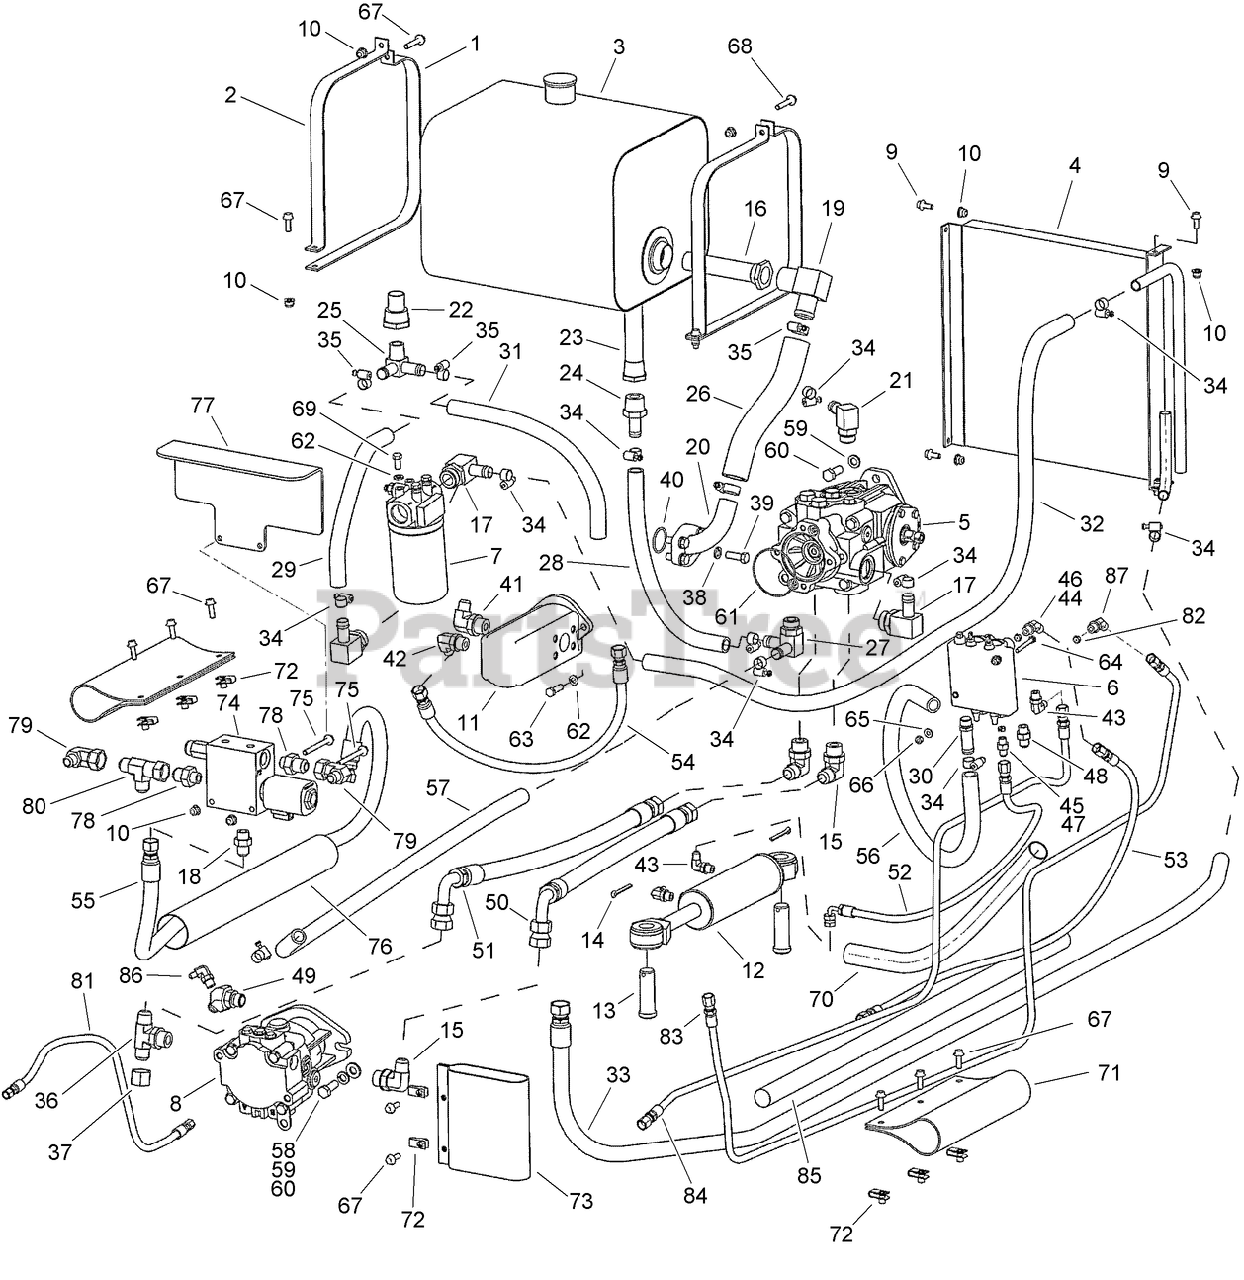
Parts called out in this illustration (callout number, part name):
1	STRAP - Tank (Lower)
2	STRAP - Tank (Upper)
3	RESERVOIR-HYDRAULIC
4	COOLER-OIL
5	HYD VARIABLE PUMP ASM
6	HYD STEERING VALVE ASM
7	OIL FILTER ASM
8	HYD PISTON MOTOR ASM
9	SCREW, METRIC FLANGE w/BODY - M8 x 20
10	NUT-TORQUE, PREVAILING
11	PUMP ASSEMBLY - Dual
12	CYLINDER ASSEMBLY - 60 (2-3/8in) ID x 127 mm (5in) Stroke, Steering
13	PIN-CLEVIS
14	PIN-COTTER
15	ELBOW-90 Adj 37FL 3/4 Tube
16	FILTER ASM
17	ELBOW - 90 Degree, 3/4 Stem End x 1-5/16-12 inch Adj O-Ring
18	CONNECTOR-Str Thd 5/8, 37FL-ORB 5/8
19	FITTING-ELBOW, 90
20	FITTING - Code 61, 90 Elbow
21	ELBOW - 90 Degree, 3/4 Stem End x 1-1/16-12 inch Adj O-Ring Boss
22	INDUCER-PRESSURE
23	FILTER ASM
24	FITTING-STRAIGHT
25	FITTING-ELBOW, LATERAL
26	HOSE - 100R3 1-1/4 in x 280 mm
28	HOSE - Hydraulic, 3/4 in x 14.5 in
29	HOSE - Hydraulic, 3/4 in x 12.5 in
30	ADAPTER - Straight, 3/4 Stem End x 3/4-16 inch Adj O-Ring
31	HOSE - 457 mm (18 inch) Long Ground Drive Pump to Reservoir (cut from D55911 bulk hose)
32	HOSE - Hydraulic, 3/4 in x 1495 mm
33	HOSE - Hydraulic, Cooler
34	CLAMP - Adj, 11/16 - 1-1/4 inch Dia
35	CLAMP - Hose Type F # 24
36	TEE - 1-1/16-12 inch Adj O-Ring Branch x Flare x Flare
38	WASHER - Spring Lock, Reg 0.438 in ZND
39	BOLT - Hex Hd .438 x 1.25 GR5 Znd
41	ADAPTOR-ELBOW
42	ELBOW-90 Deg, 1/2 to 5/8
43	ELBOW-90 DEG (ADJUSTABLE 37 DEG)
44	PLATE-ORIFICE
45	PLATE-ORIFICE
46	ELBOW-45 Adj 37FL 3/8 Tube
47	CONNECTOR-Str Thd 3/8, 37FL-ORB 3/8
48	CONNECTOR-Str Thd 1/2, 37FL-ORB 1/2
49	FITTING - 45 degree, Special
50	HOSE - 660 mm (26 inch) Long, Ground Drive Pump to Ground Drive Motor
51	HOSE - 660 mm (26 inch) Long, Ground Drive Pump to Ground Drive Motor
52	HOSE - 737 mm (29in) Long, Valve to Steering Cylinder, Closed End
53	HOSE - 940 mm (37 inch) Long, Valve to Steering Cylinder, Rod End
54	HOSE - 610 mm (24 inch) Long, Pump to Steering Control Valve
55	HOSE - 5/8 x 1600
56	HOSE - 800 mm (31-1/2 in), Return, Steering Control Valve to Dual Pump
57	HOSE - 800 mm (31-1/2 in), Return, Steering Control Valve to Dual Pump
59	WASHER-Spring Lock Reg 1/2 ZND
60	BOLT-Hex Hd 1/2 x 1-1/4 GR5 ZND
62	WASHER-Spring Lock, Reg 3/8 ZND
63	BOLT
64	BOLT-1/4-20 x 2
65	WASHER-FLAT
66	NUT - Prev Trq 1/4 GRC ZND Direct
67	SCREW-HH
68	SCREW, METRIC FLANGE w/BODY - M8 x 45
69	SCREW-HH
70	SLEEVE - Hose Retaining, Protective, Hose
71	BOOT-HOSE
73	BOOT-HOSE
74	3 WAY HYD PLOW VALVE ASM
75	SCREW, METRIC FLANGE w/BODY - M8 x 80
76	SLEEVE - Hose Protector
77	PLATE - Heat Shield
78	CONNECTOR-Str Thd 3/4, 37FL-ORB 5/8
79	FITTING-ELBOW, 90
80	FITTING-TEE
81	ASSEMBLY - Hose
82	ORIFICE
83	ASSEMBLY - Hose
84	ASSEMBLY - Hose
85	SLEEVE - Hose Protector
86	ELBOW - 90 Degree, 9/16-18 flare x 1/4 inch PT
87	ELBOW-90 Deg
